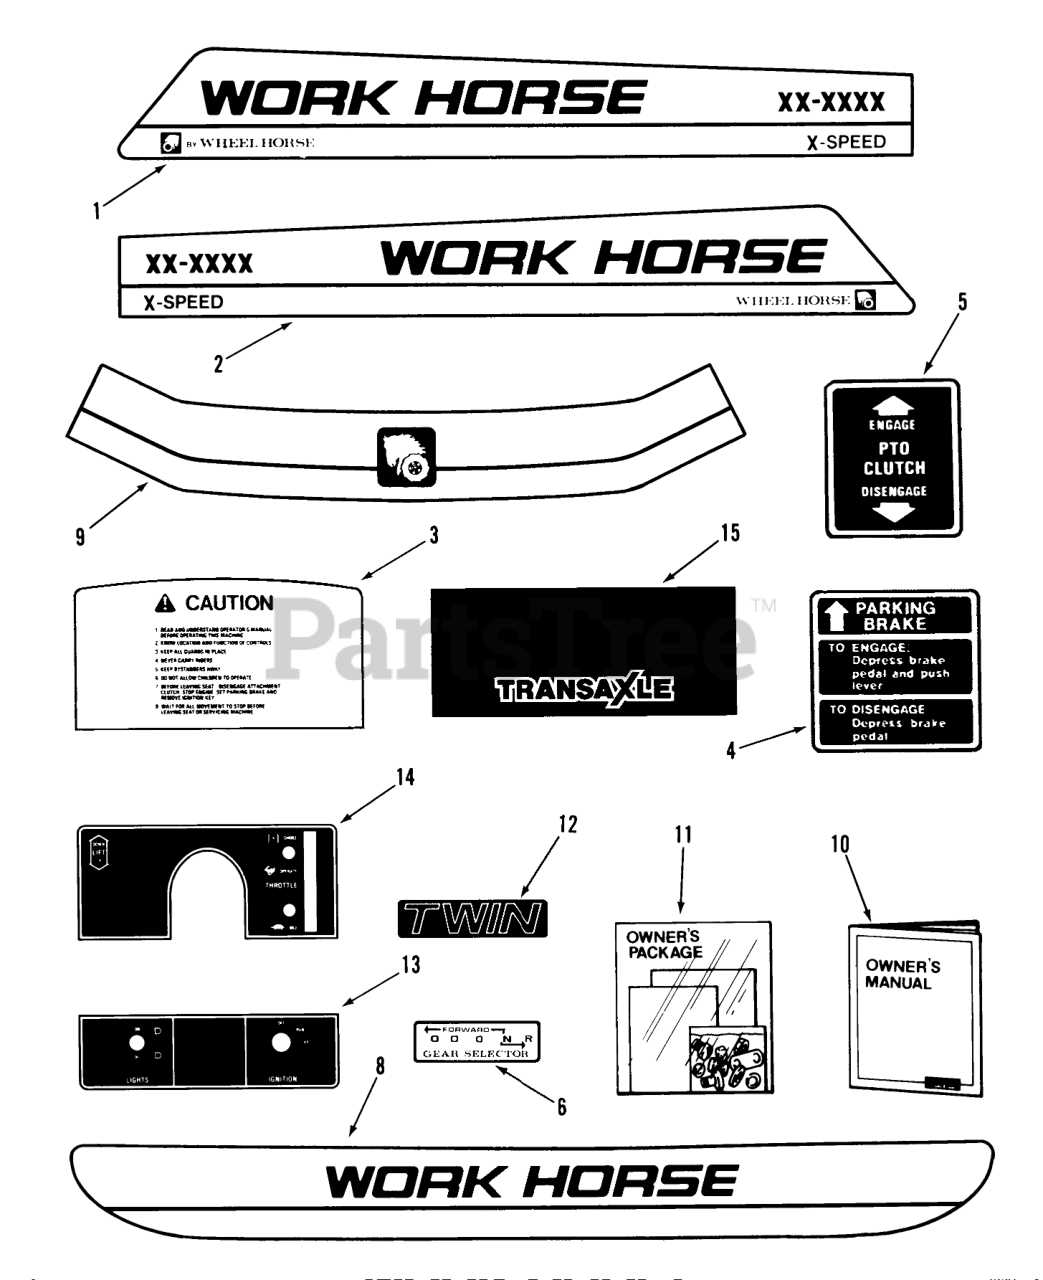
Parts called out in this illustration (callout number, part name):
1	Decal-Hood RH LT-1100-3-Speed Only
1	Decal-Hood RH LT-1100-5-Speed Only
1	HOOD DECAL RH
2	HOOD DECAL LH
2	Decal-Hood LH LT-1100-5-Speed Only
2	Decal-Hood LH LT-1600 Only
3	DECAL - CAUTION
4	Decal Parking Brake
5	DECAL-PTO CLUTCH
6	DECAL-SHIFT
8	Decal Rear
9	DECAL - HOOD FRONT
10	Owner-s Manual-Tractor
11	New Tractor Loose Parts Package LT-1100-3-Speed Only
11	New Tractor Loose Parts Package LT-1100-5-Speed Only
11	New Tractor Loose Parts Package LT-1600 Only
12	Decal-Engine LT-1600 Only
13	DECAL-BACK PLATE-SWI
14	DECAL - LOWER DASH
15	DECAL - TRANSAXLE
